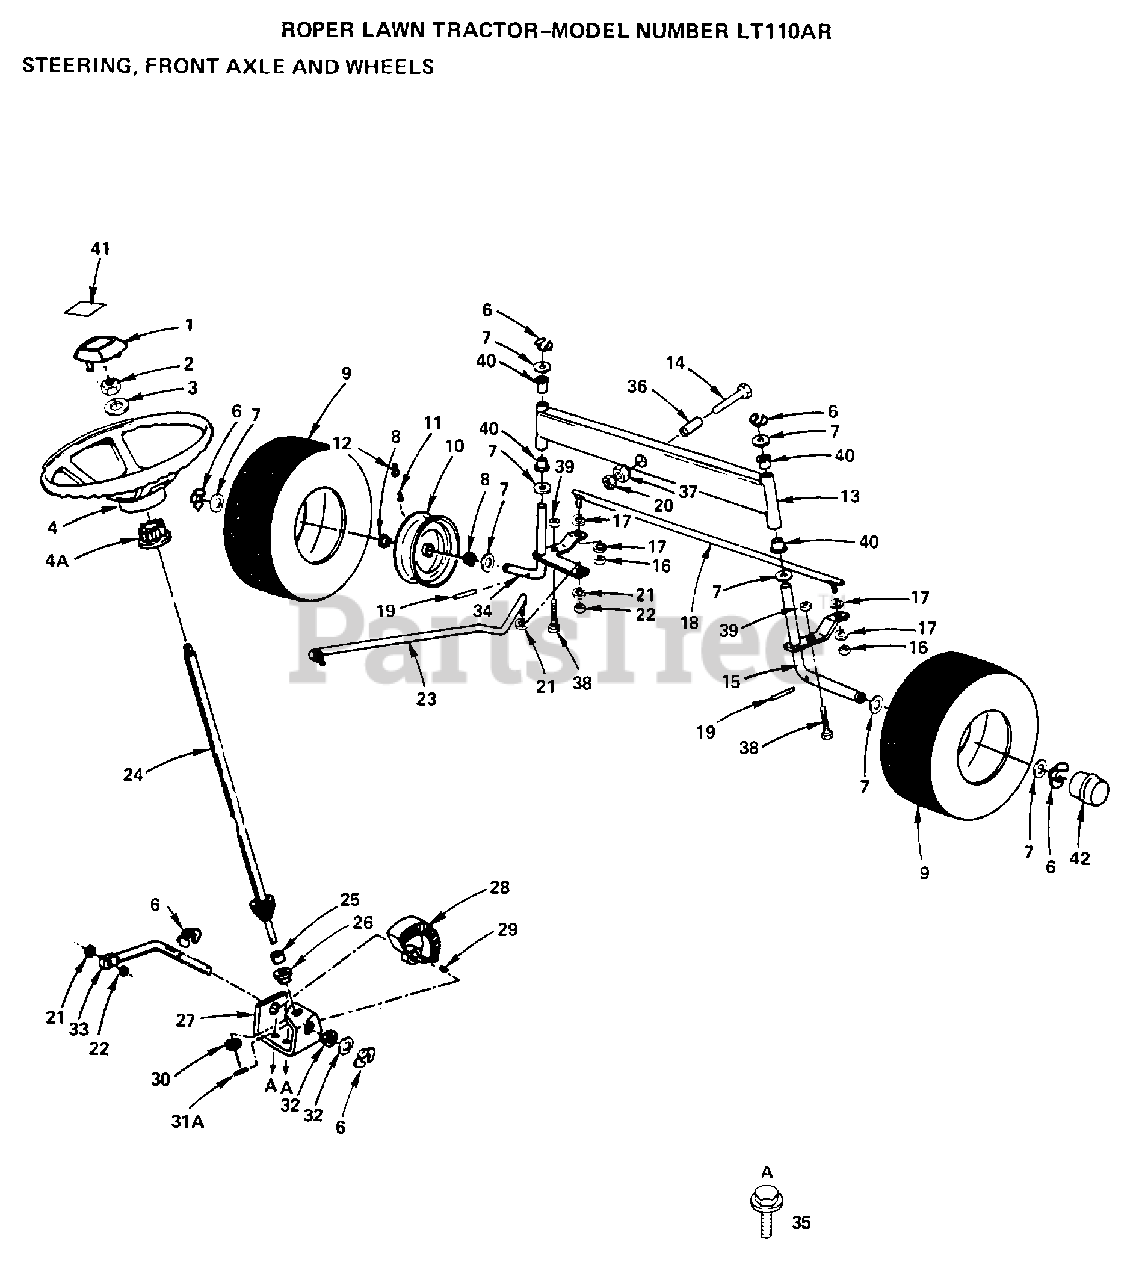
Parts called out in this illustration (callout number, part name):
1	INSERT-WHEEL LT
2	NUT
3	WASHER
4A	ADAPTER LT
6	RING
8	"FLANGE, BEARING"
11	VALVE STEM LT
12	VALVE CAP
13	AXLE ASSY YTV
16	NUT
17	LOCKWASHER
20	LOCKNUT M
21	LOCKWASHER
23	DRAG LINK LTV
24	SHAFT ASSY LT
25	SHAFT SPACER LT
26	BUSHING
28	GEAR-SECTOR T
30	WASHER D
32	WASHER .T
33	ROD STEERING LT
34	SPINDLE LH LTV
35	SCREW
38	BOLT
39	NUT
40	COL. SRTG. BEAR.
41	DECAL - STEERING WHEEL
42	HUB CAP
